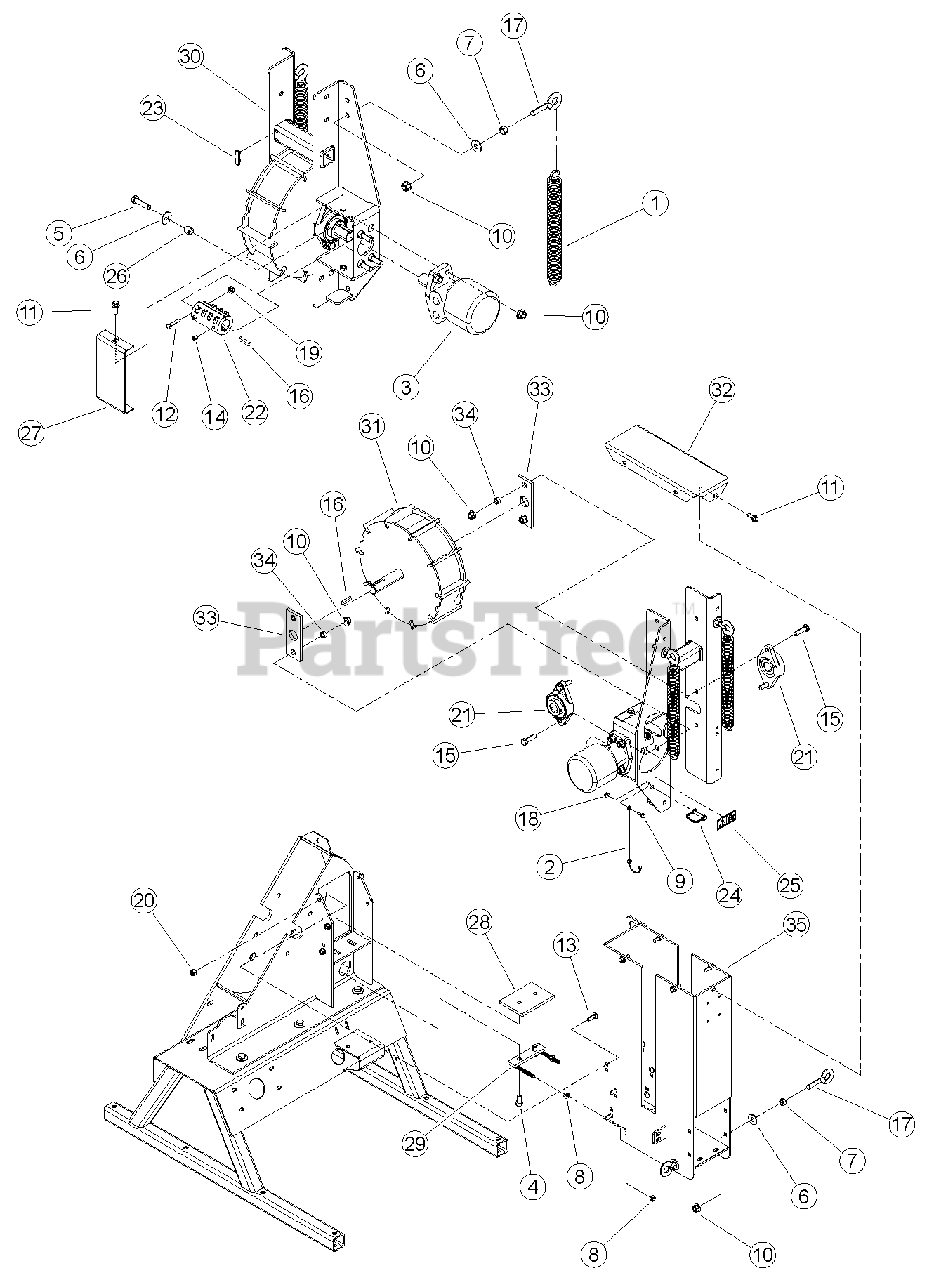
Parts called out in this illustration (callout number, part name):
1	SPRING, EXTENSION
2	LANYARD, NYLON
3	MOTOR, 32.7 CU IN HYDRAULIC
4	BOLT, 1/2 X 1 GR5 HEX CPSCREW ZP
5	BOLT, 1/2 X 2 GR5 HEX CAPSCREW ZP
6	WASHER, 1/2" FLAT ZP
7	NUT, 1/2" HEX NC ZP
8	NUT, 3/8" SERRATED FLANGE NC ZP
9	BOLT, 1/4-20 X 3/4 HWH GR5 CZP
10	NUT, 1/2-13 NYLOCK FLANGE
11	BOLT, 3/8 X 1 FLANGE NC
12	BOLT, 5/16 X 1-1/2 GR5 HEX CPS ZP
13	BOLT, 3/8 X 1-1/4" GR5 CRG NC ZP
14	SET SCREW, 3/8 X 1/2 CUP PT SKT
15	BOLT, 1/2 X 1 3/4 GR5 HCPS NC ZP
16	KEY, 5/16 X 1-1/2 SQUARE
17	EYEBOLT, 1/2 X 2" ZP
18	NUT, 1/4-20 NYLOCK-FLANGE
19	NUT, 5/16-18 NYLOCK-FLANGE
20	NUT, 3/8-16 NYLOCK FLANGE
21	BEARING 1-1/4" DIA 2 BOLT FLANGE
22	COUPLER 1-1/4 SHAFT
23	WEAR PAD,STD.SPRING HD FRONT
24	PIN, SNAP 3/8 X 1-1/2 USABLE LGH
25	DECAL, CRUSHING ISO
26	SPACER, 0.75 X 0.620
27	SHIELD, COUPLER
28	ANVIL, 4 INCH CHIPPER
29	WELDMENT, BLOCK ADJUSTOR
30	WELDMENT, ROLLER SLIDE
31	WELDMENT, TOP GRAB ROLLER
32	WELDMENT, TOP ROLLER COVER
33	BEARING, SLIDE
34	SPACER, .75 OD X .5 ID X .37
35	WELDMENT, ROLLER SUPPORT 5 IN
